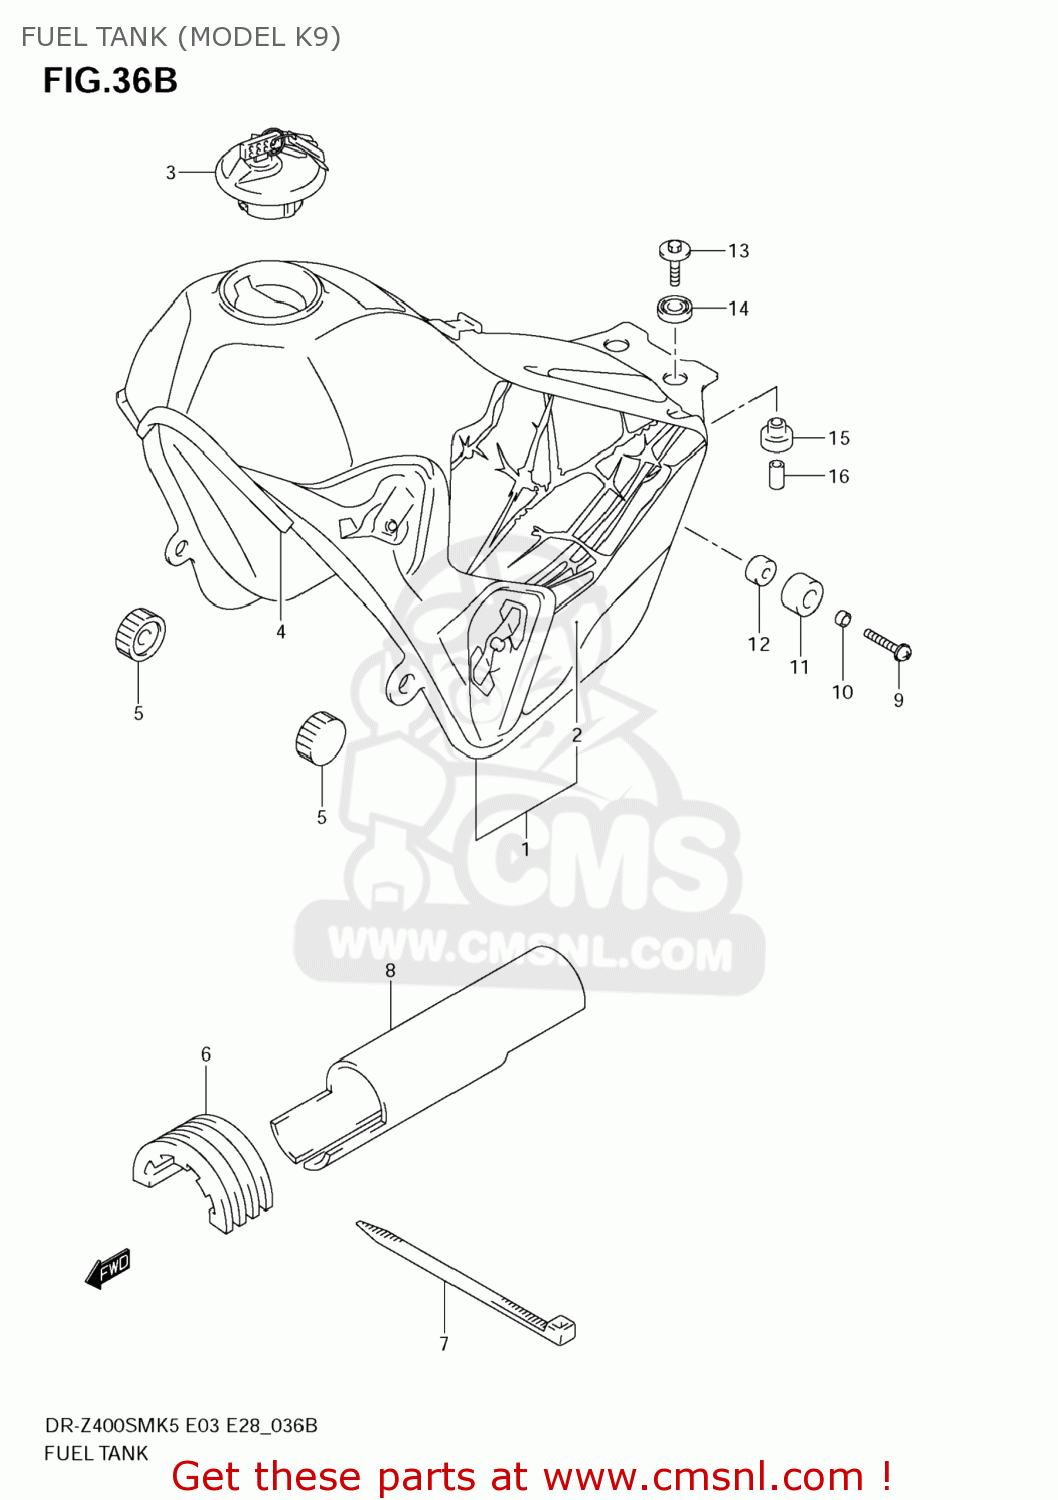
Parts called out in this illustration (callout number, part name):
1	TANK ASSY,FUEL(BLACK)
2	TAPE SET,FUEL TANK
3	CAP SET,FUEL TANK
4	MOLDING
5	CUSHION
6	CUSHION,FUEL TANK
7	CLAMP(L:300)
8	SHIELD,FUEL TANK
9	SCREW
10	SPACER(6.5X20X9)
11	CUSHION
12	SPACER(6.5X9X5)
13	BOLT(6X30)
14	CUSHION
15	CUSHION
16	SPACER(6.5X9X18)
